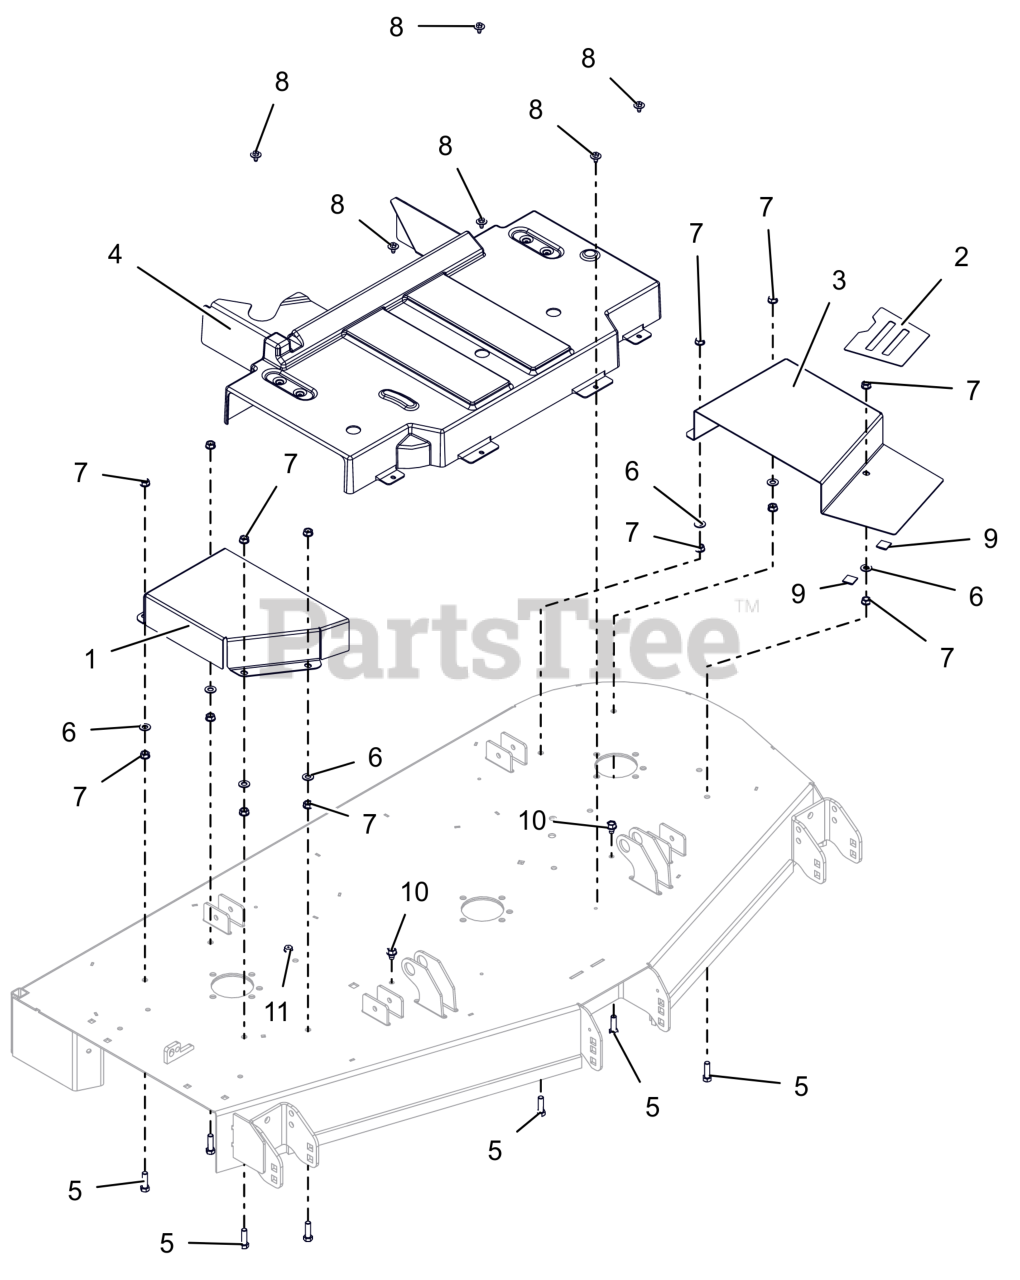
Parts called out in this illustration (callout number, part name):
1	GUARD,BELT 52" RIGHT CE
2	GRIP TAPE 52-60 BELT COVER
3	GUARD, BELT 60" LEFT CE (ORANGE)
4	GUARD, CENTER DECK SPINDLE CE
5	BLT, HEX .38-16X1.25 G5 ZCC
6	WSHR,FLT .406X.812X.065 ZCC
7	NUT, SPNLK-FLG .38-16 G5 ZCC
8	SCR, TAP .25-20X.50 LG HWH ZCC
10	SCR,TAP .375-16X.50 HWH TR ZCC
11	SCR,TAP .312-18X.50 HWH TR ZCC
